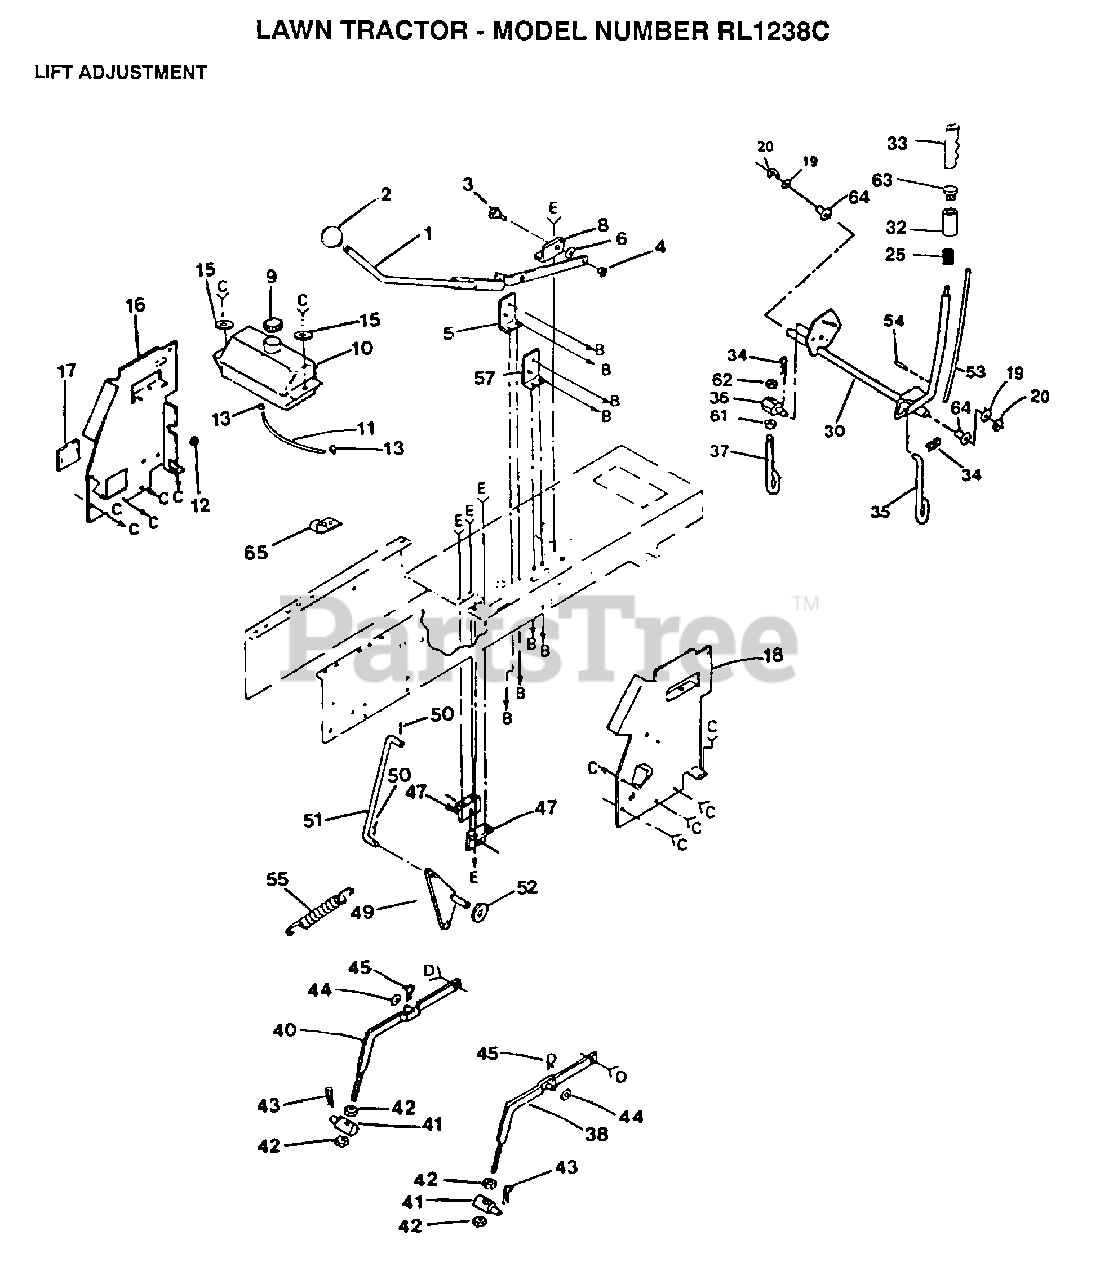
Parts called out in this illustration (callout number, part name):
3	"BOLT, SHOULDER LT"
5	"BRACKET,SWITCH LT"
7	SCREW
8	"SUP,LVR,CLUTCH LT"
10	TANK.FUEL.LT.
11	FUEL LINE T
12	SNAP BUSHING T
13	HOSE CLAMP
14	SCREW
15	WASHER GT
16	PANEL DASH LH
17	COVER ACCESS
19	WASHER
33	GRIP
35	LIFT LINK LT
37	PIVOT PIN T
38	RH SUSP ARM ASM
39	"BOLT, SHOULDER LT"
40	LH SUSP ARM ASM
42	NUT
43	SPRING H
45	SPRING.RETAINER
47	"BRKT,BELLCRAN T"
49	"T, BELLCRANK"
50	COTTER PIN
51	ROD CLUTCH T
52	WASHER
54	PIN-GROOVE LT
57	BRACKET LT
59	WASHER T
60	NUT SPECIAL T
61	NUT
64	NYLON BEARING
65	INSUL CLIP T
